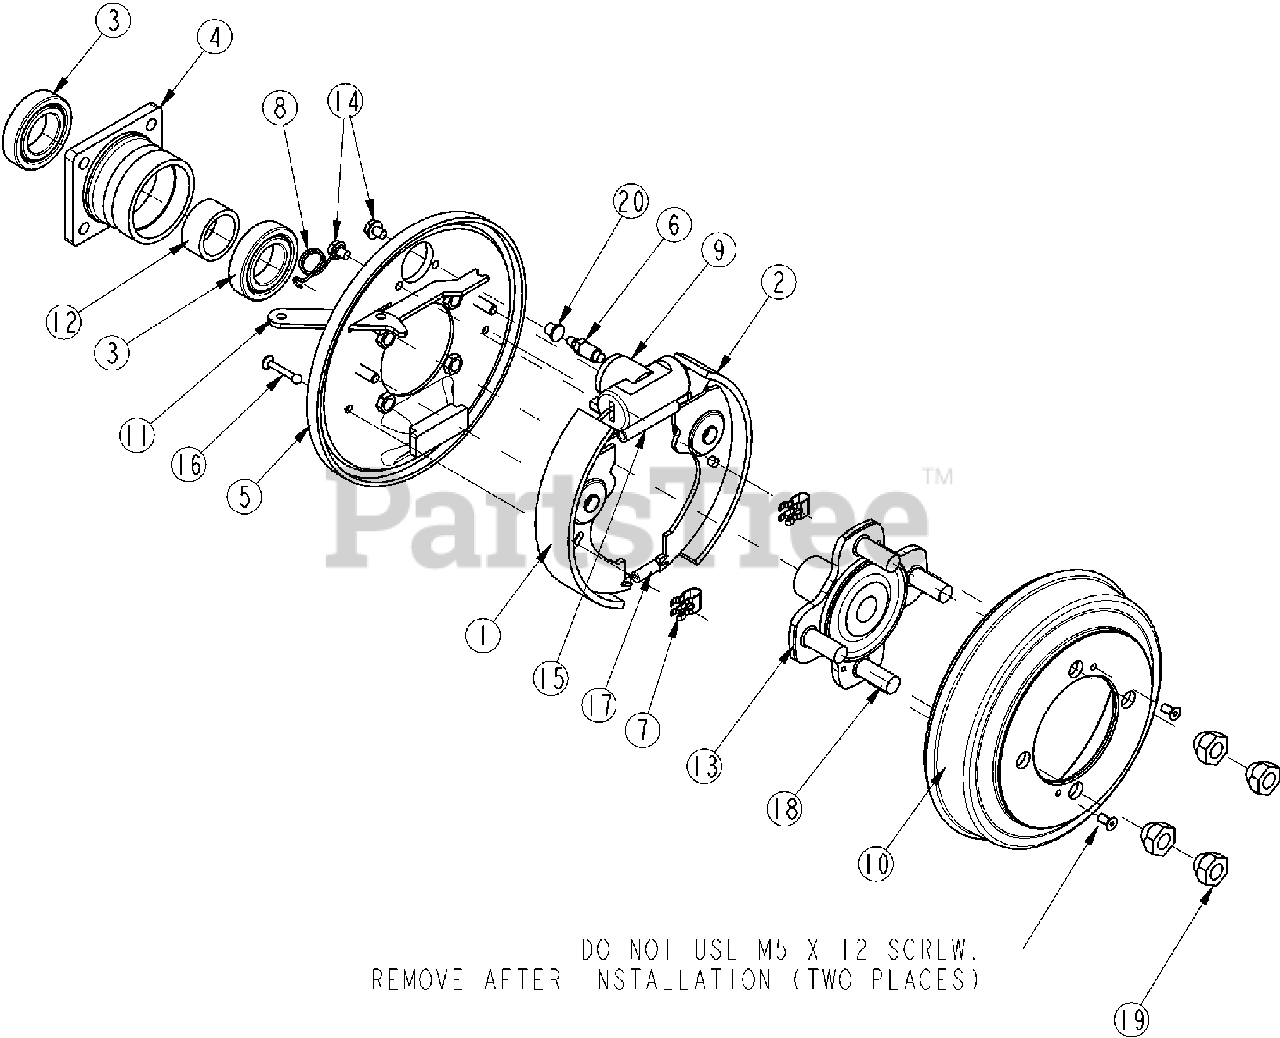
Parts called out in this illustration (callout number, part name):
1	LEFT SHOE
2	RIGHT SHOE
3	BALL BEARING
4	BEARING HOLDER HUB
5	BRAKE SHOE DISC RH
5	BRAKE SHOE DISC LH
6	BLEEDER SCREW
7	SHOES LOCKING SPRING
8	RIGHT SPRING/HAND BRAKE LEVER
8	LEFT SPRING/HAND BRAKE LEVER
9	HYDRAULIC CYLINDER
10	DRUM
11	RIGHT LEVERS SET
11	LEFT LEVERS SET
12	CMX SPACER
13	BRAKE FLANGE HUB W/STUDS
14	SCREW M6 x 40
15	UPPER RETURN SPRING
16	SPRING PIN
17	LOWER RETURN SPRING
18	STUD
19	NUT, LUG 1/2-20 x 60-Degree
20	BOOT
